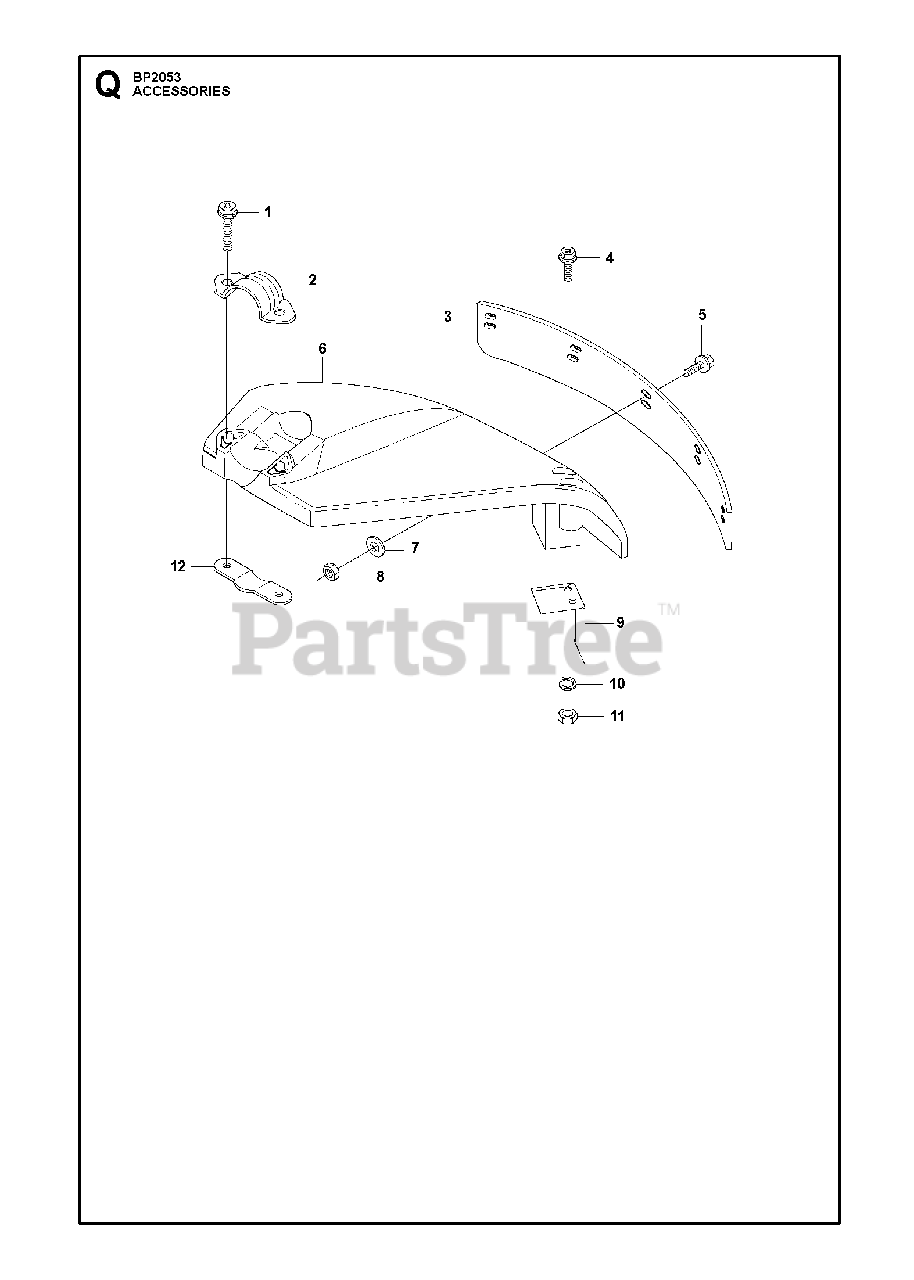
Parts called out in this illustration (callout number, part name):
1	SCREW M6S 6X30
7	WASHER
10	SPRING WASHER
